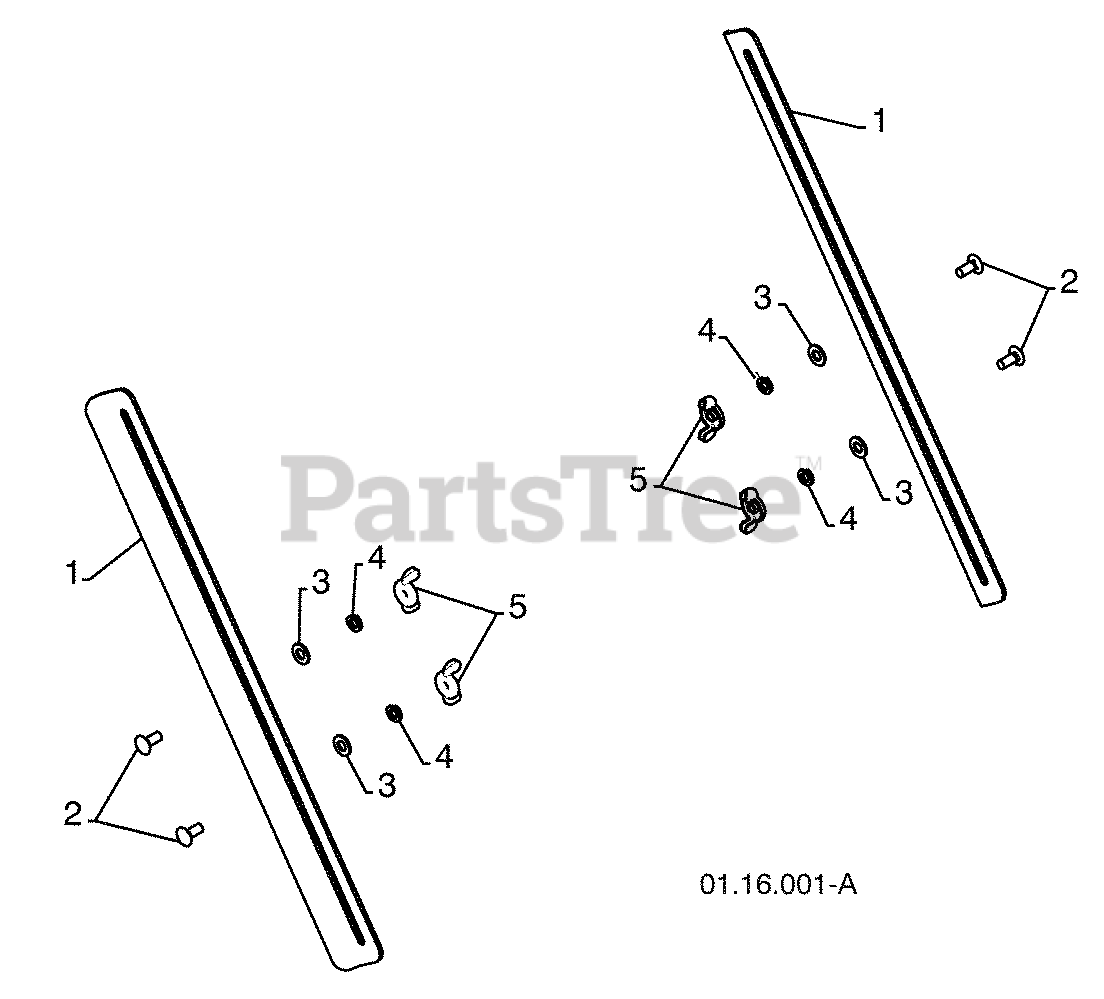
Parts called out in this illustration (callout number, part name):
1	DRIFT CUTTER BAR
2	CARRIAGE BOLT 5/16-18 X .750
3	PLASTIC WASHER
4	LOCKWASHER 5/16
5	NUT 5/16-18
